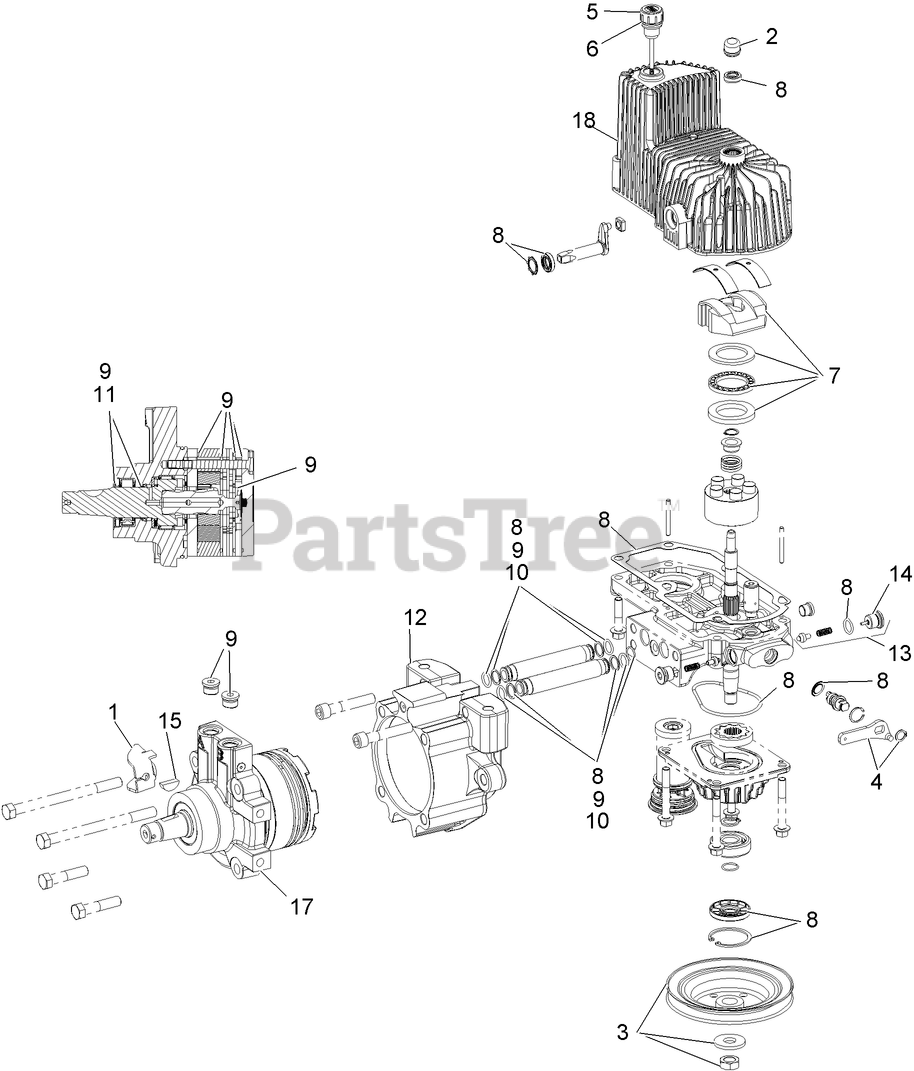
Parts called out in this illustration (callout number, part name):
1	BRACKET-ANCHOR, CABLE
2	COVER-SHAFT, HYDRO
3	PULLEY KIT
4	HANDLE-BYPASS VALVE, HYDRO
5	DIPSTICK-HYDRO W/GASKET
6	GASKET-DIPSTICK, HYDRO
7	SWASH BLOCK KIT
8	PUMP SEAL KIT
9	MOTOR SEAL KIT
10	TUBE SEAL KIT
11	OUTPUT SHAFT SEAL KIT
12	NOSECUP-DRY
13	CHECK VALVE ASM
14	PLUG-CHECK (W/O-RING)
15	KEY-WOODRUFF
17	MOTOR-HYD, LH
18	HOUSING-HYDRO, LH
